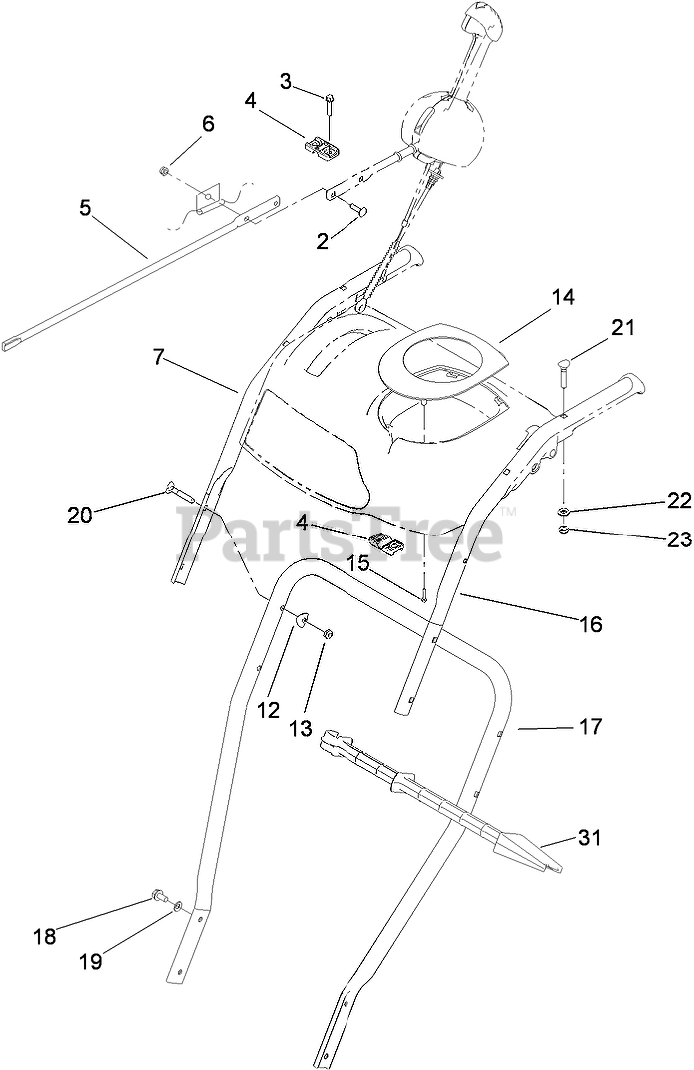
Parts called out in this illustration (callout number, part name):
2	SCREW-CARR
3	SCREW-PLASTITE
4	SUPPORT-ROD
5	ROD-CHUTE, FRONT
6	NUT-LOCK, NI
7	HANDLE-UPPER, RH
12	WASHER
13	NUT-LOCK, NI
14	COVER-PANEL, CONTROL
15	SCREW-PPH
16	HANDLE-UPPER, LH
17	HANDLE-LOWER
18	SCREW-HWHTF
19	WASHER-BELLEVILLE
20	SCREW-HANDLE
21	SCREW-HANDLE
22	WASHER-FLAT
23	NUT-LOCK, NI
31	STICK-CLEANOUT
